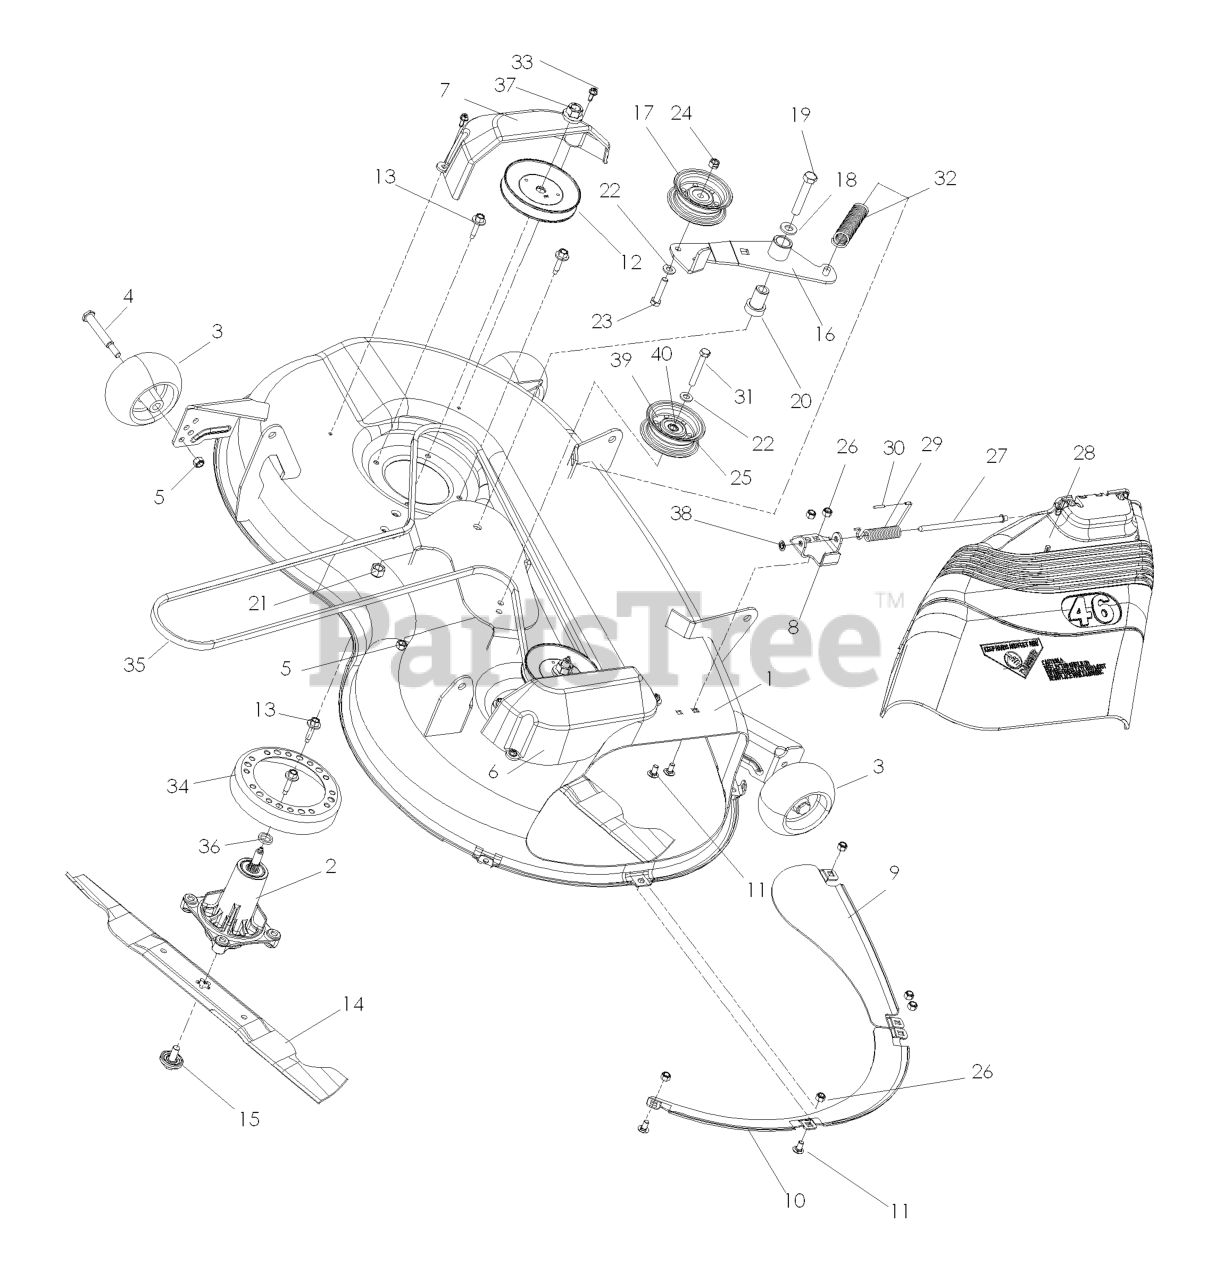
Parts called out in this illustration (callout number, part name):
1	DECK W/DECALS 46 ORANGE
2	MANDREL GREASABLE
3	GAUGE WHEEL
4	SHOULDER BOLT 1/2X2-5/8 ZD SPE
5	NUT 3/8-16 NYLOC
6	COVER.MANDREL.RH.46"
7	COVER.MANDREL.LH.46"
8	BRKT.DEFLECTOR.38"2005+
9	BAFFLE CENTER FRONT
10	BAFFLE FRONT RH
11	CARRIAGE BOLT 5/16C X 5/8"
12	PULLEY
13	WASHER HEAD SCREW
14	BLADE.MOWER.46".HI.LIFT
15	BOLT.WASHER.ASM.7/16-2
16	DECK IDLER ARM WELDMENT
17	PULLEY, IDLER, SHORT
18	WASHER 1/2" FLAT
19	HCS 1/2C X 2 3/4
20	IDLER SPINDLE
21	NUT 1/2-13 HEX NYLOC ZD
22	WASHER 3/8 SAE FLAT
23	HCS 3/8-16 X 1 3/4 GR5
24	NUT 3/8C CENTERBLOCK
25	IDLER PULLEY ASM
26	NUT 5/16 NYLOC
27	ROD, HINGE
28	SHIELD.DEFLECTOR.MOWER.46"BLAC
29	SPRING, TORSION DEFLECTOR
30	CAP-SLEEVE
31	HCS 3/8C X 2 1/2
33	SCREW- 1/4-20 X 5/8
34	STRIPPER-ROUND-UNIVERSAL
36	WASHER-SPACER
37	LOCKNUT - 9/16
38	PUSH NUT
39	PULLEY, IDLER
40	BEARING INSERT
